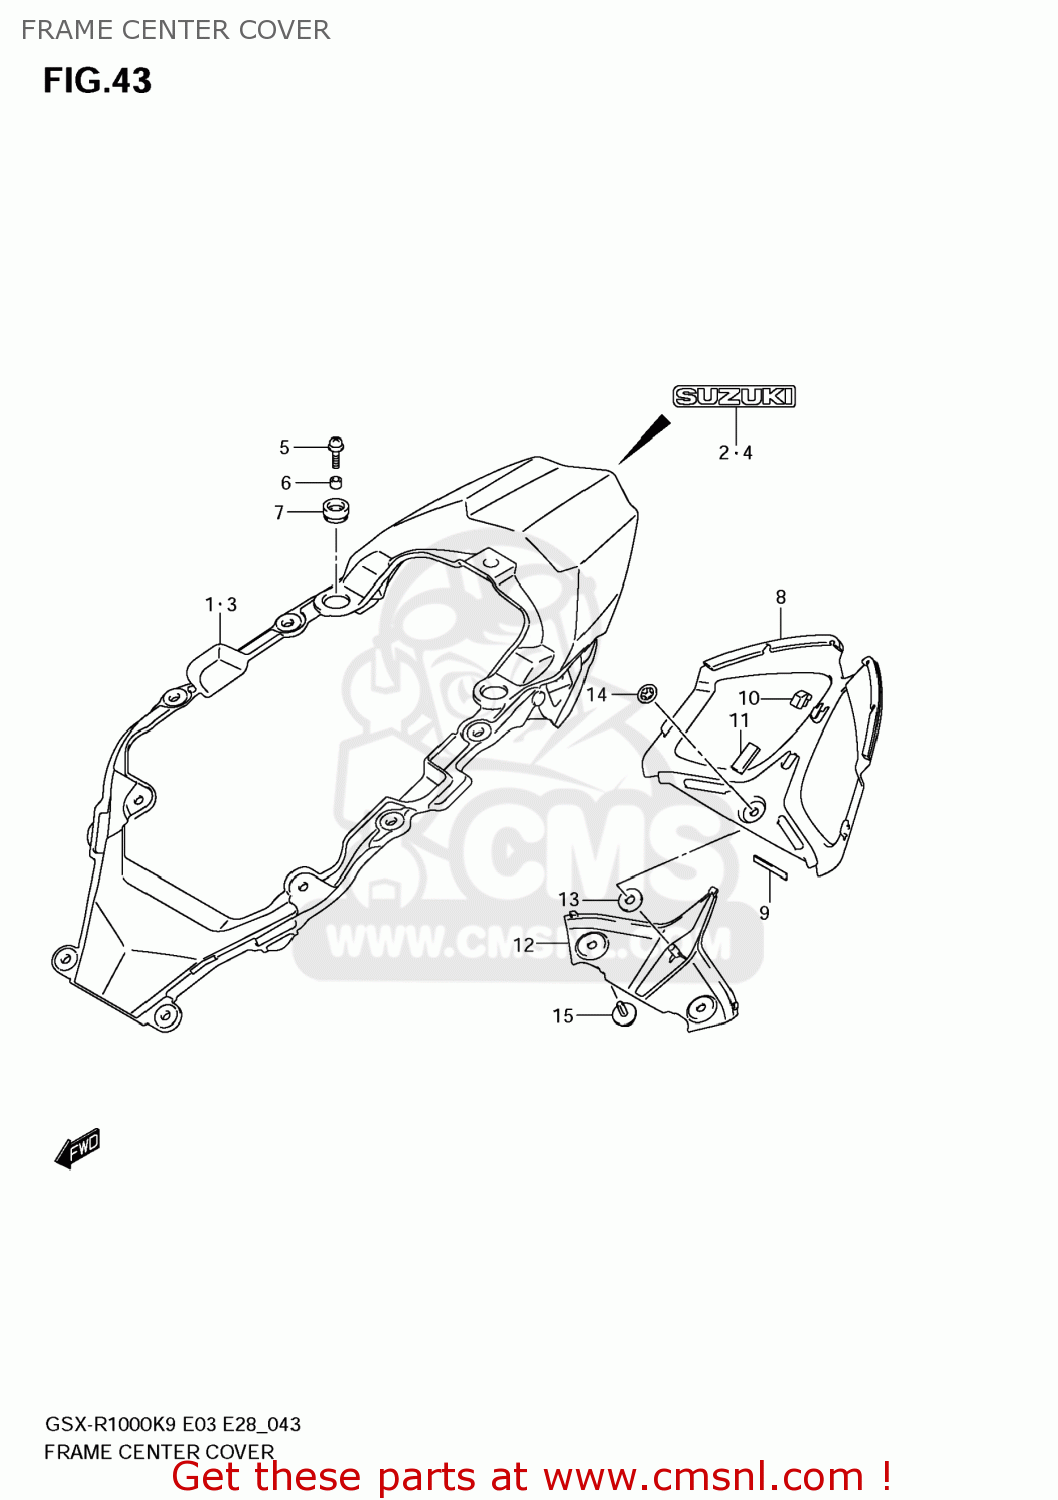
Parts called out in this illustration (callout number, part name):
1	COVER ASSY,FRAME CTR
2	EMBLEM,SUZUKI
3	COVER ASSY,FRAME CTR
4	EMBLEM,SUZUKI
5	SCREW(6X16)
6	SPACER(6.5X10X7)
7	CUSHION,FRAME COVER RR
8	COVER,FRAME RR CTR
9	CUSHION,FRAME COVER RR CTR
10	CUSHION,FRAME COVER RR CTR
11	CUSHION,CTR PANEL UPR
12	COVER,FRAME RR CTR LWR
13	CUSHION
14	NUT
15	CLIP
